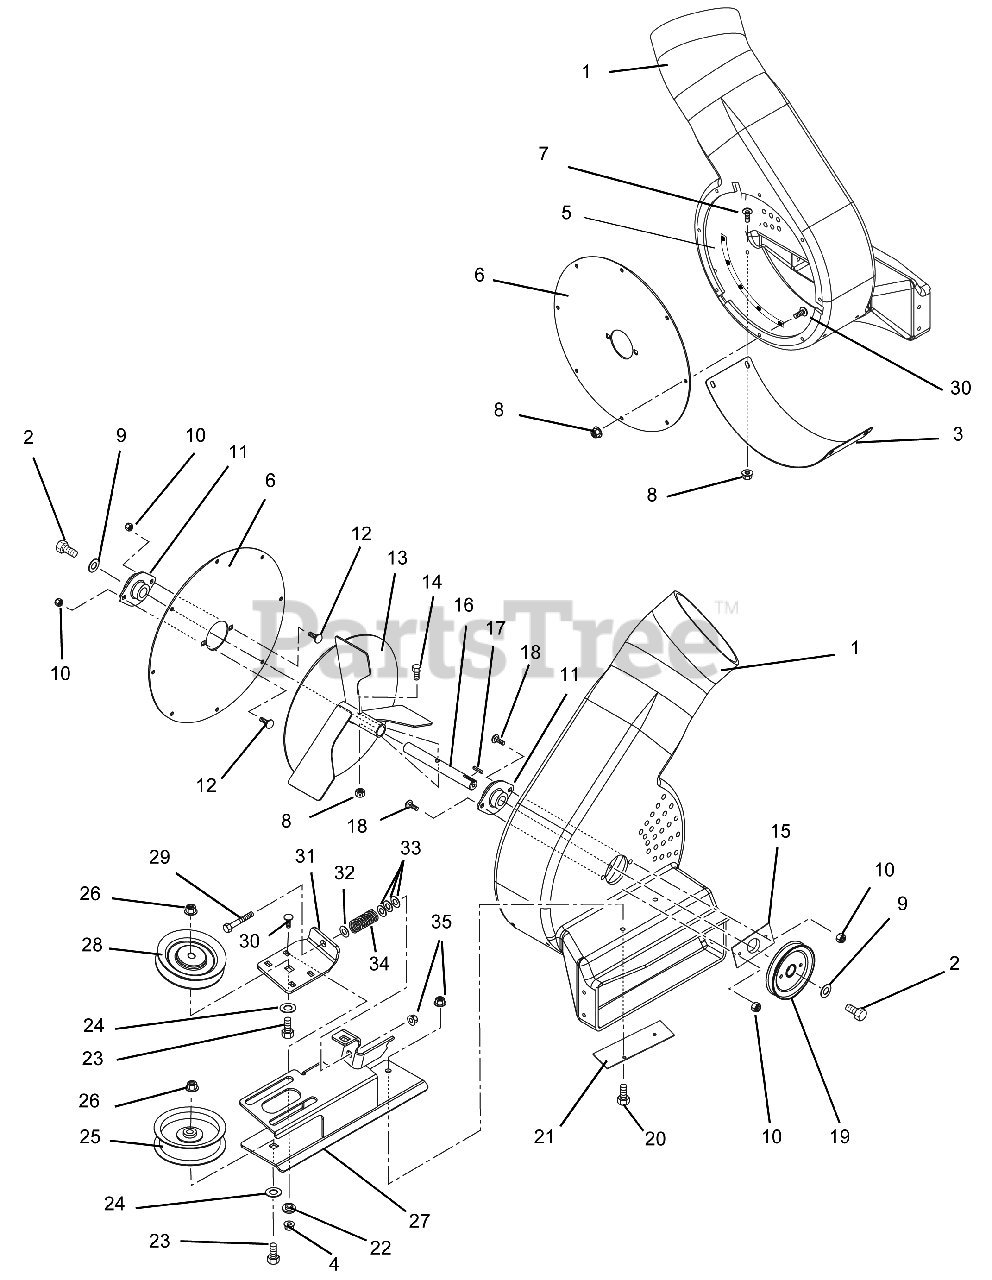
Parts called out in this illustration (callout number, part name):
1	BLOWER (SERVICE ASSEMBLY)
2	BLT-HEX .25-20X.50 GR5 EPOXY
3	PLATE, SKID
4	@NUT-LK-TOP-FLG .25-20 YWZC
5	MTG BOLT REINFORCING PLT - BLK
6	PLATE, BEARING MOUNT
7	SCR-MCH .25-20X.75 TXTR YWZC
8	@NUT-LK-NYL-FLG .25-20 YWZC
9	WSHR-FL-STL .344X1.125X.135
10	@NUT-LK-NYL-FLG .31-18 YWZC
11	BEARING, 2 BOLT FLANGE -.75 ID
12	@BLT-RDHDSQNK .31-18X.75 G5YZ
13	WELDMENT, IMPELLER, 3 BLADE
14	BLT-HEX .25-20X1.50 GR8 YWZC
15	BEARING WASHER PLATE - BLK
16	SHAFT, IMPELLER
17	KEY-SQ .187 X .50 X .187
18	@BLT-RDHDSQNK .31-18X1.00 G5YZ
19	SHEAVE, BLOWER - 4.25 DIA.
20	BOLT-HEX.31-18X.875 YWZC GR5
21	PLATE,BACK
22	BSHG-FLG .265X.437X.250X.750
23	@BLT-HEX .38-16X1.75 GR5 YWZC
24	@WSHR-FL-STL.406X.812X.065 YWZ
25	IDLER, FLG .38ID X 3.50
26	@NUT-LK-TOP-FLG .38-16 YWZC
27	WELDMENT, IDLER MOUNT
28	V-IDLER, 4.00X.38
29	@BLT-HEX .31-18X4.00 GR5 YWZC
30	@BLT-RDHDSQNK .25-20X.75 G5YZ
31	BRACKET, ADJUSTABLE IDLER
32	NUT-PUSH .312
33	WSHR-FL-STL .406X1.00X.188 YWZ
34	SG-COMP .092X.77X3.13 WLD 36
35	@NUT-LK-TOP-FLG .31-18 YWZC
36	BLOWER (SERVICE ASSEMBLY)
